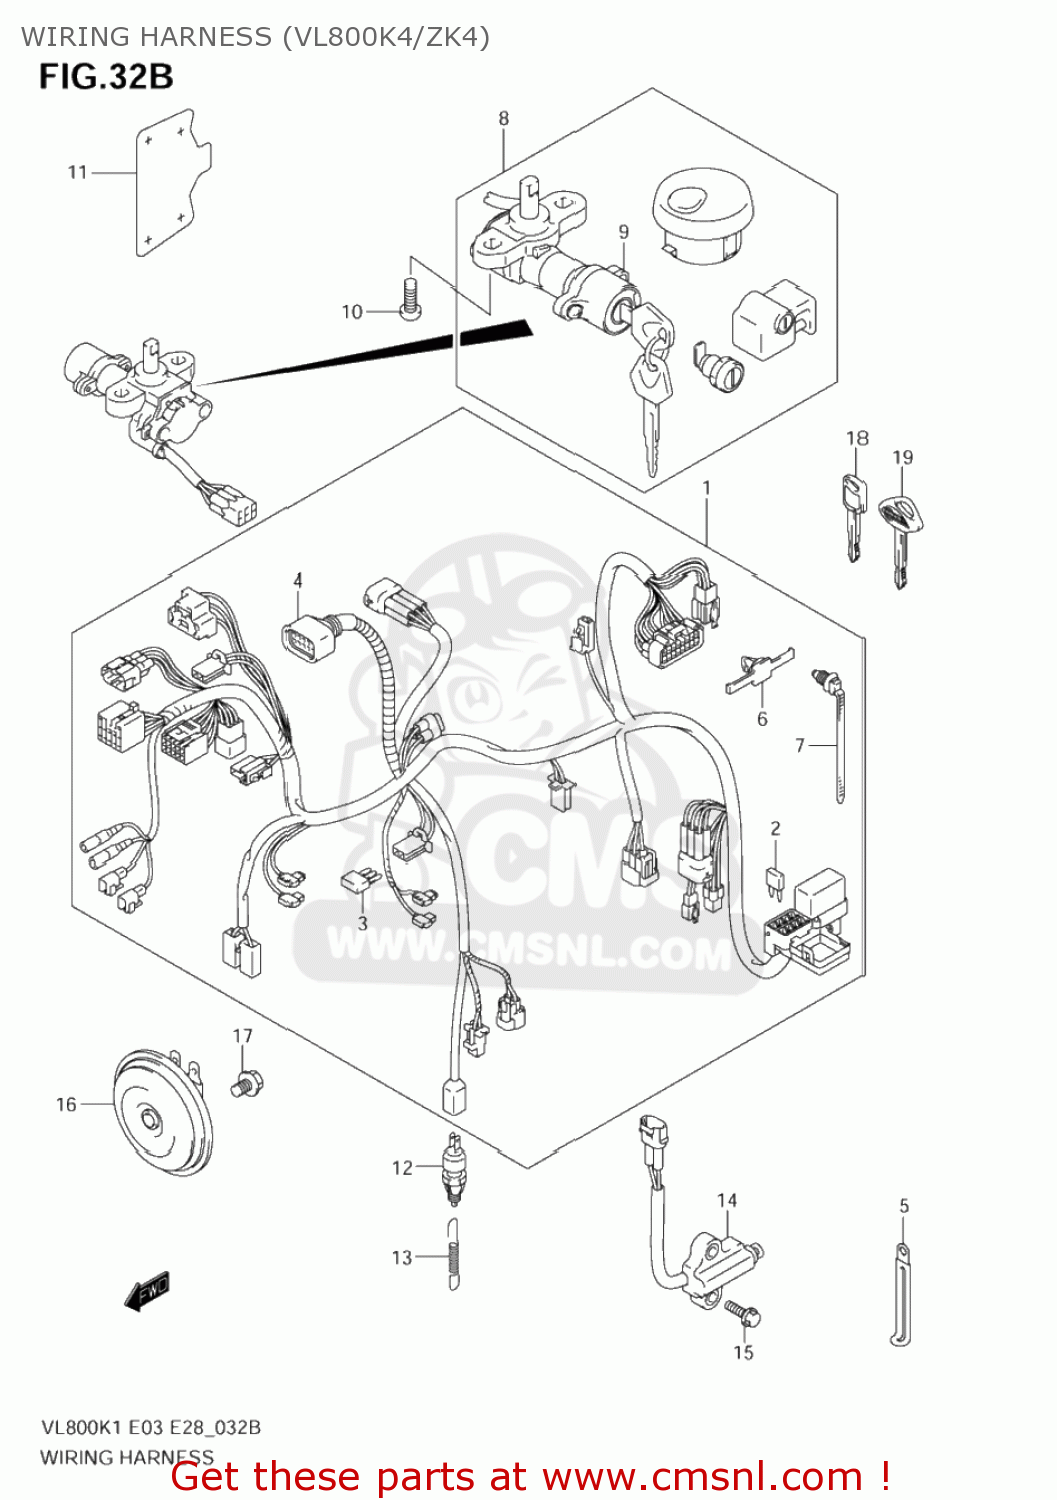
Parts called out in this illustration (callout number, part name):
1	HARNESS,WIRING
2	FUSE(10A)
3	DIODE(STANLEY DE8804)
4	COVER,SPEEDOMETER COUPLER
5	CLAMP(L:80)
6	CLAMP
7	CLAMP(L:154)
8	LOCK SET
9	LOCK ASSY,STEERING
10	BOLT(8X20)
11	PROTECTOR,IGNITION SWITCH
12	SWITCH ASSY,STOP LAMP
13	SPRING
14	SWITCH ASSY,SIDE STAND
15	BOLT
16	HORN ASSY
17	BOLT
18	KEY,BLANK
19	KEY,BLANK(VOLUSIA)
